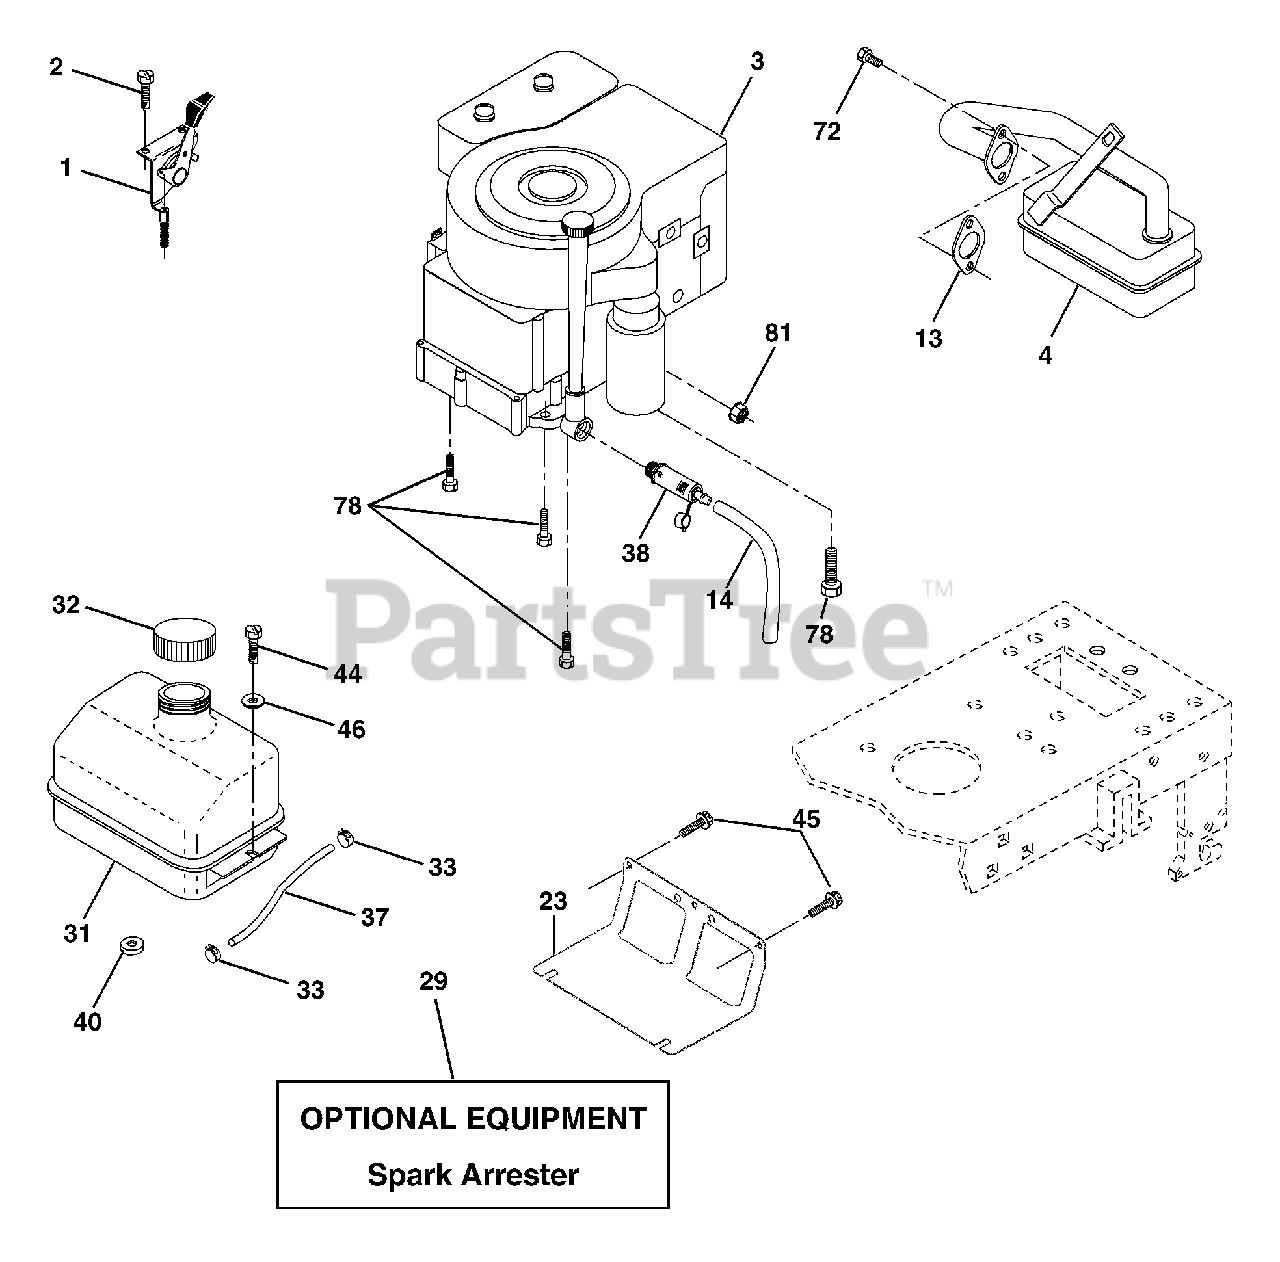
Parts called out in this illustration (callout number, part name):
1	Control Throttle /Choke Flag
2	Screw Hex Thd Cut 1/4-20 x 1/2
4	Muffler Exhaust B&S Lt
13	Gasket 1 313 Id Tin Plated
14	Tube Drain Oil Easy
23	Shield Browning/Debris Guard
29	Arrestor Spark
31	Tank Fuel 1 25 Fr
32	Cap Asm Fuel W/sym Vented
33	Clamp Hose Blk
37	Line Fuel 20"
38	Plug Drain Oil Easy
40	Bushing Snap Nyl Blk Fuel Line
44	Screw Hexwsh Thdrol 1/4-20 x 3/4
45	Screw Hex Wsh Thdrol 3/8-16
46	Washer 9/32 X 7/8 X 16 Ga.
72	Screw Socket Head 5/16-18 x 1
78	Screw Thdrol 3/8-16 x 1-1/4
81	Nut Keps Hex 1/4-20 unc
